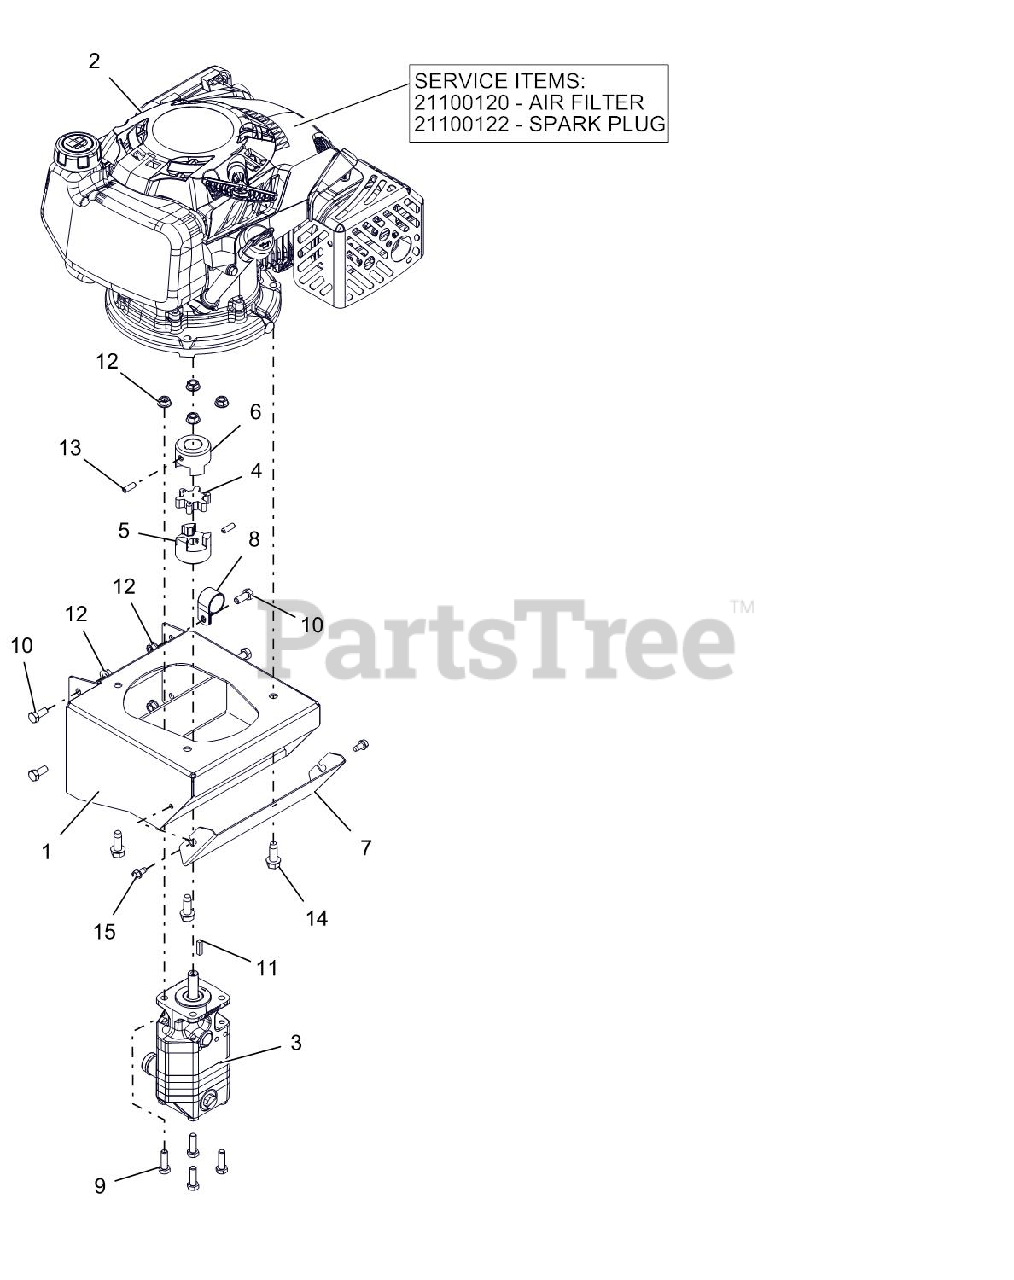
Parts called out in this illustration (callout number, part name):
1	ENGINE MOUNT W/SAFTY DECAL-22T
2	ENGINE, SUBARU EA175V
2	FILTER, AIR- SUBARU PAPER
2	PLUG, SPARK
3	PUMP,SPLITTER-11 GPM
4	SPIDER - URETHANE
5	COUPLER - DRIVE 1/2"
6	COUPLER - DRIVE, 7/8"
7	COVER, COUPLING
8	CLAMP, COUSHIONED STEEL REV
9	@BLT-HEX .31-18X1.00 GR5 YWZC
10	@BLT-HEX .31-18X.75 GR5 YWZC
11	KEY-SQ .188X.75X.188
12	@NUT-LK-TOP-FLG .31-18 YWZC
13	SCR,SET .25-20X.75 PCPT SH
14	@SCR-TAP .38-16X1.00 HWH TR YZ
15	SCR-TAP .25-20X.50 HWH TR YWZ
